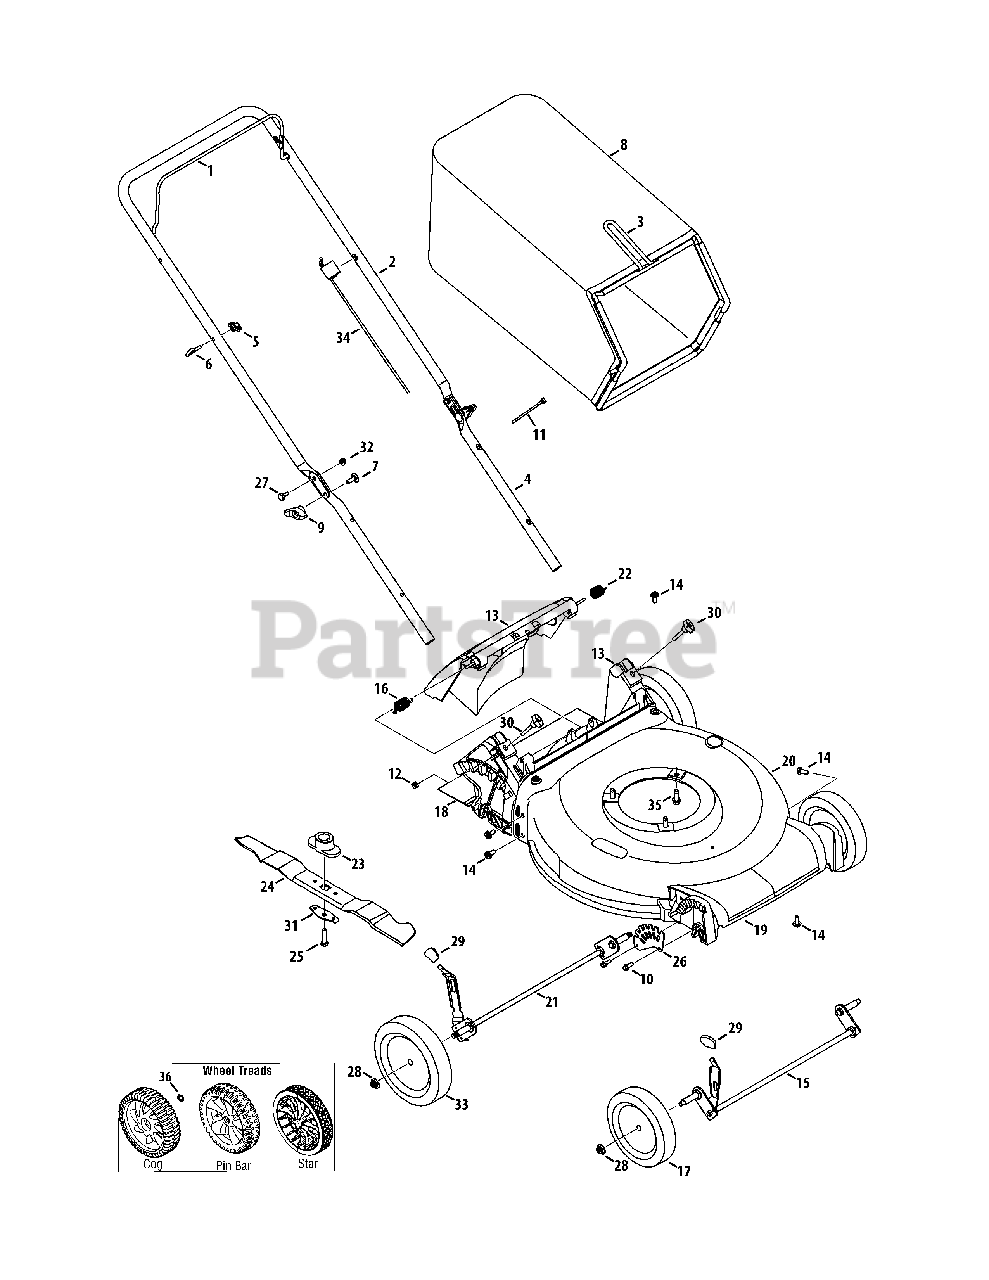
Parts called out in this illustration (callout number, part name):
1	Blade Control
2	Upper Handle
3	Grass Catcher Frame
4	Lower Handle
5	Wing Nut
6	Rope Guide
7	Carriage Screw ,5/16-18
8	Grass Bag (Yardman logo)
8	Grass Bag - Black
9	Wing Knob
10	Screw, 1/4-15 x .750
11	Cable Tie
12	Nut, Sq., 1/4-20
13	Rear Door Assembly
13	Rear Door Assembly (Home Depot Label)
14	Screw, 5/16-14 x .750
15	Front Axle Assembly
16	Torsion Spring - RH
17	Front Wheel, 7 x 1.8, Bar, Gray
17	Front Wheel, 7 x 1.8, Star, Gray
17	Front Wheel, 7", Cog
18	Trail Shield
19	Front Cover
20	Deck - 21" - Red
20	Deck - 21" - Green
20	Deck - 21" - Black
21	Rear Axle Assembly
22	Torsion Spring - LH
23	Blade Adapter
23	Blade Adapter (Honda)
24	Mulching Blade
25	Screw , 3/8-24 x 1.50
26	Front Height Adjuster Plate
27	Sldr. Screw, .375 x .126 x 1/4-20
28	Flange Lock Nut, 3/8-16
29	Adjustment Lever Knob
30	Wing Nut
31	Blade Bell Support
32	Nut, Flange Lock, 1/4-20
33	Rear Wheel, 8 x 1.8, Bar, Gray
33	Rear Wheel, 8 x 1.8, Star, Gray
33	Rear Wheel, 8", Cog
34	Control Cable (Briggs)
34	Control Cable, 36.65" (Honda)
34	Control Cable, 61.15" (139cc engine)
35	TT Sems Screw, 3/8-16 x 1.0
36	Wave Washer, .510 x .750 x .017
